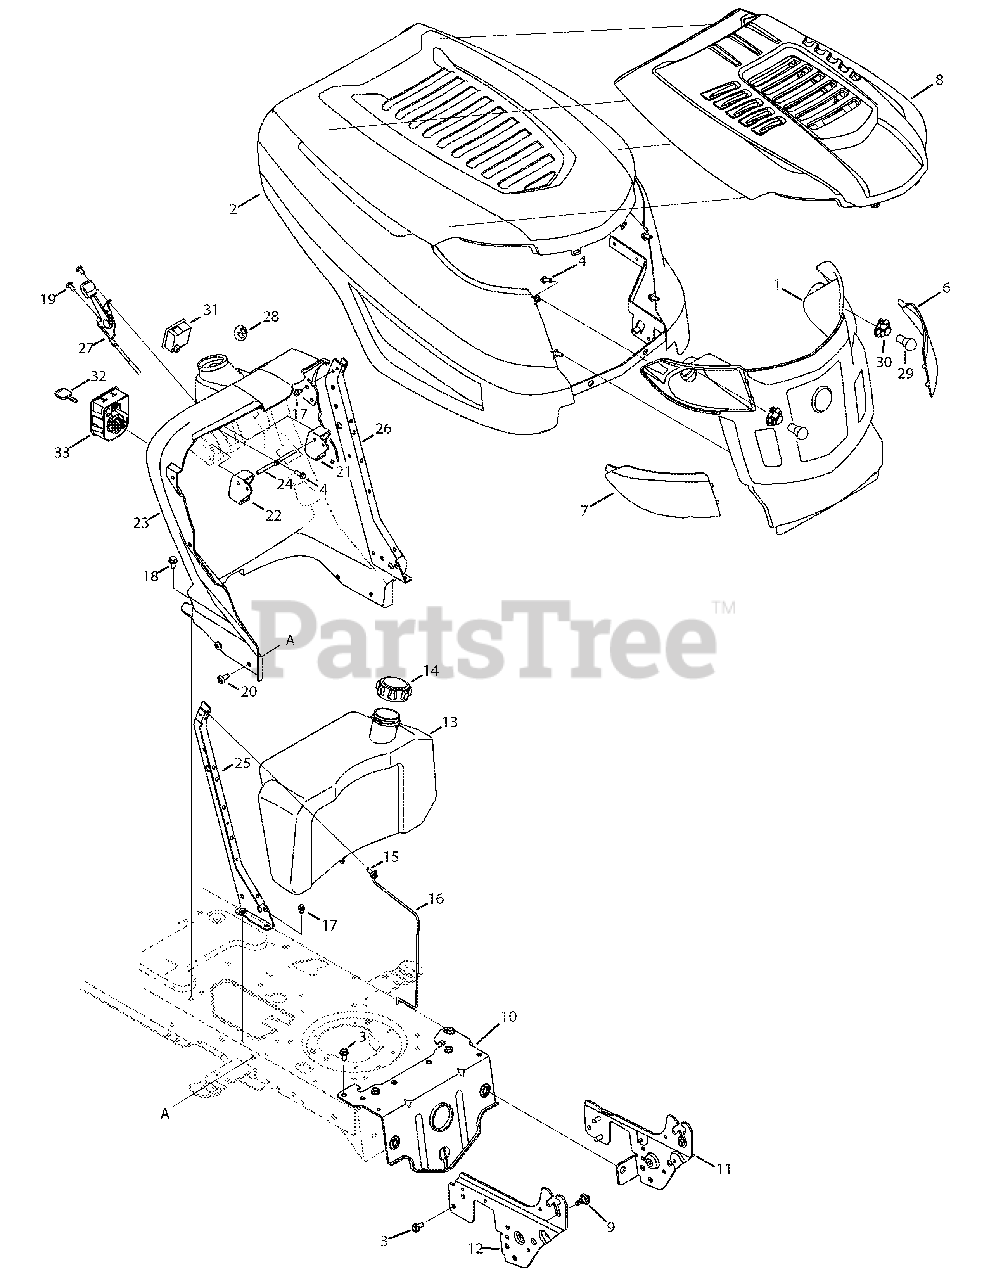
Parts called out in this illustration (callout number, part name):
1	Grill Assembly
3	Screw, 5/16-18, 0.625
4	Self-tapping Screw, 1/4-15 x.75
6	Headlight Lens (LH)
7	Headlight Lens (RH)
8	TB Hood Scoop
9	Shoulder Screw,.43 x.29
14	Fuel Tank Cap
15	Screw, 1/4-20, 0.750
16	Gas Tank Support Rod
17	Screw, 1/4-20, 0.500
18	Screw, 5/16-18 x 0.500
19	Screw, 1/4-14 x.625
20	Screw, 5/16-18 x.75
21	Parking Brake Button
22	Cruise Control Button
23	Dash Panel w/ Manual PTO
23	Dash Panel w/ Electric PTO
24	Brake/Cruise Pivot Rod
27	Throttle/Choke Cntrl. Cable
27	Throttle Cable
28	Choke Plug
29	Headlamp, 12V
30	Lamp Socket
31	Systems Ind. Monitor w/ Amtr.
32	Ignition Key w/ plastic cover
33	Module, Ignition Switch
